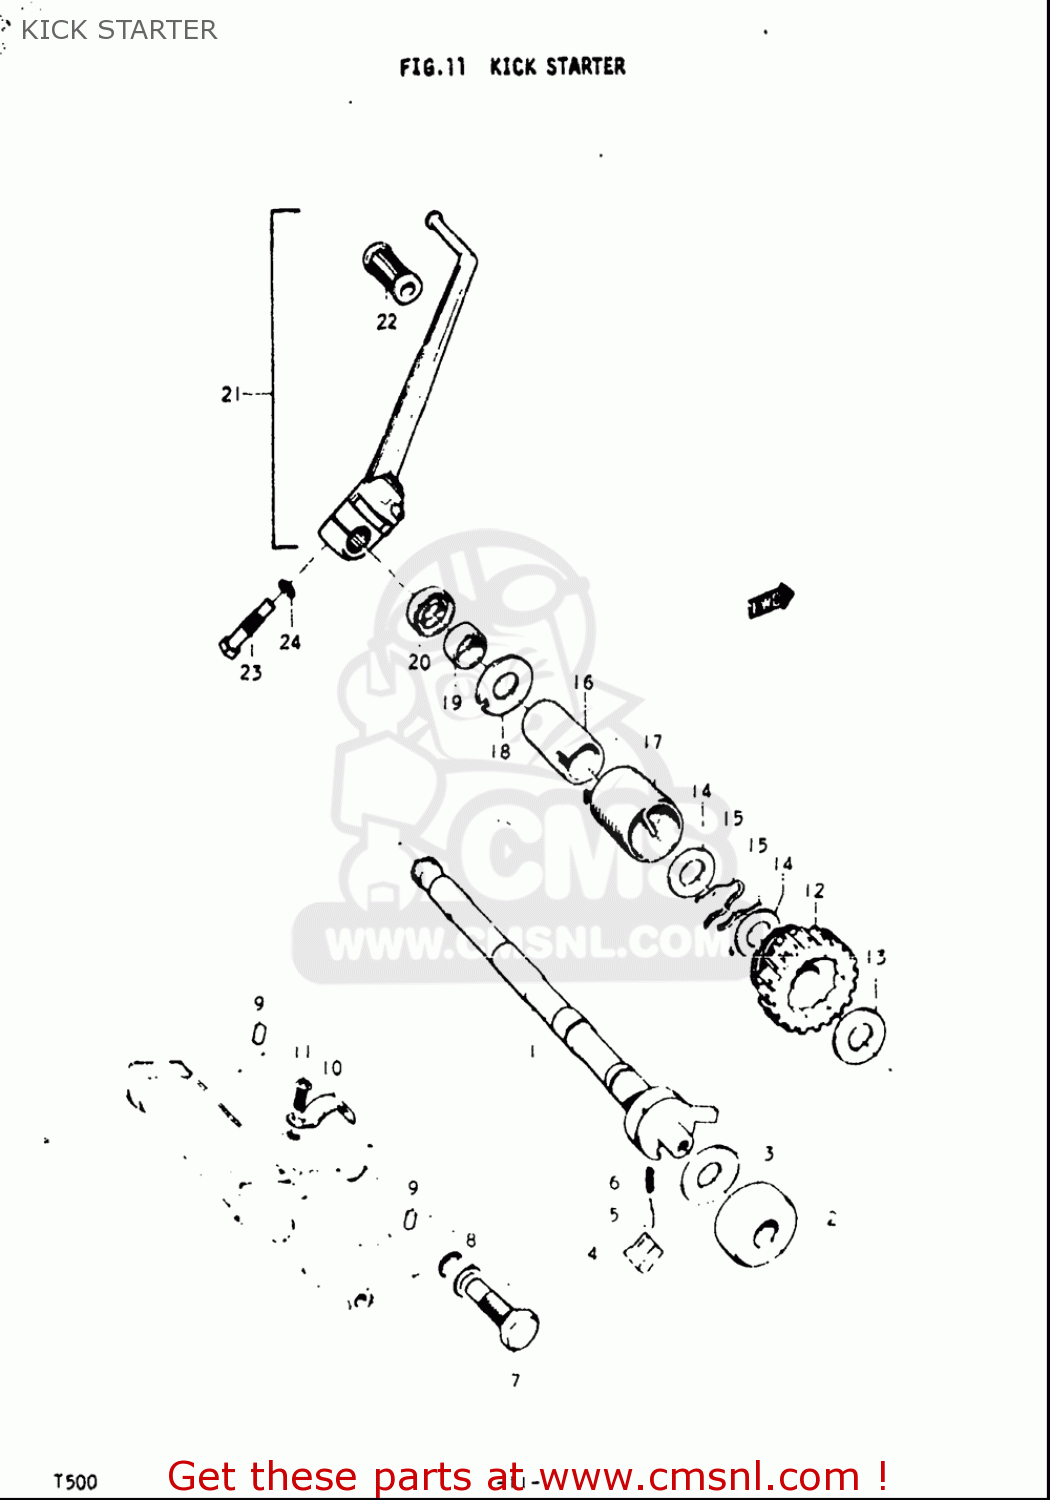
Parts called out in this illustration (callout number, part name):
3	WASHER(13X31.5X1.5)
4	PAWL,KICK STARTER
5	PIN(5X15.5)
6	SPRING
8	WASHER(14.5X22X1.6)
9	PIN
11	SCREW
14	WASHER(16X30X1)
17	SPRING
20	SEAL,OIL(16X30X8)
22	RUBBER,KICK STARTER PEDAL
23	BOLT(10X37.5)
24	WASHER,LOCK
